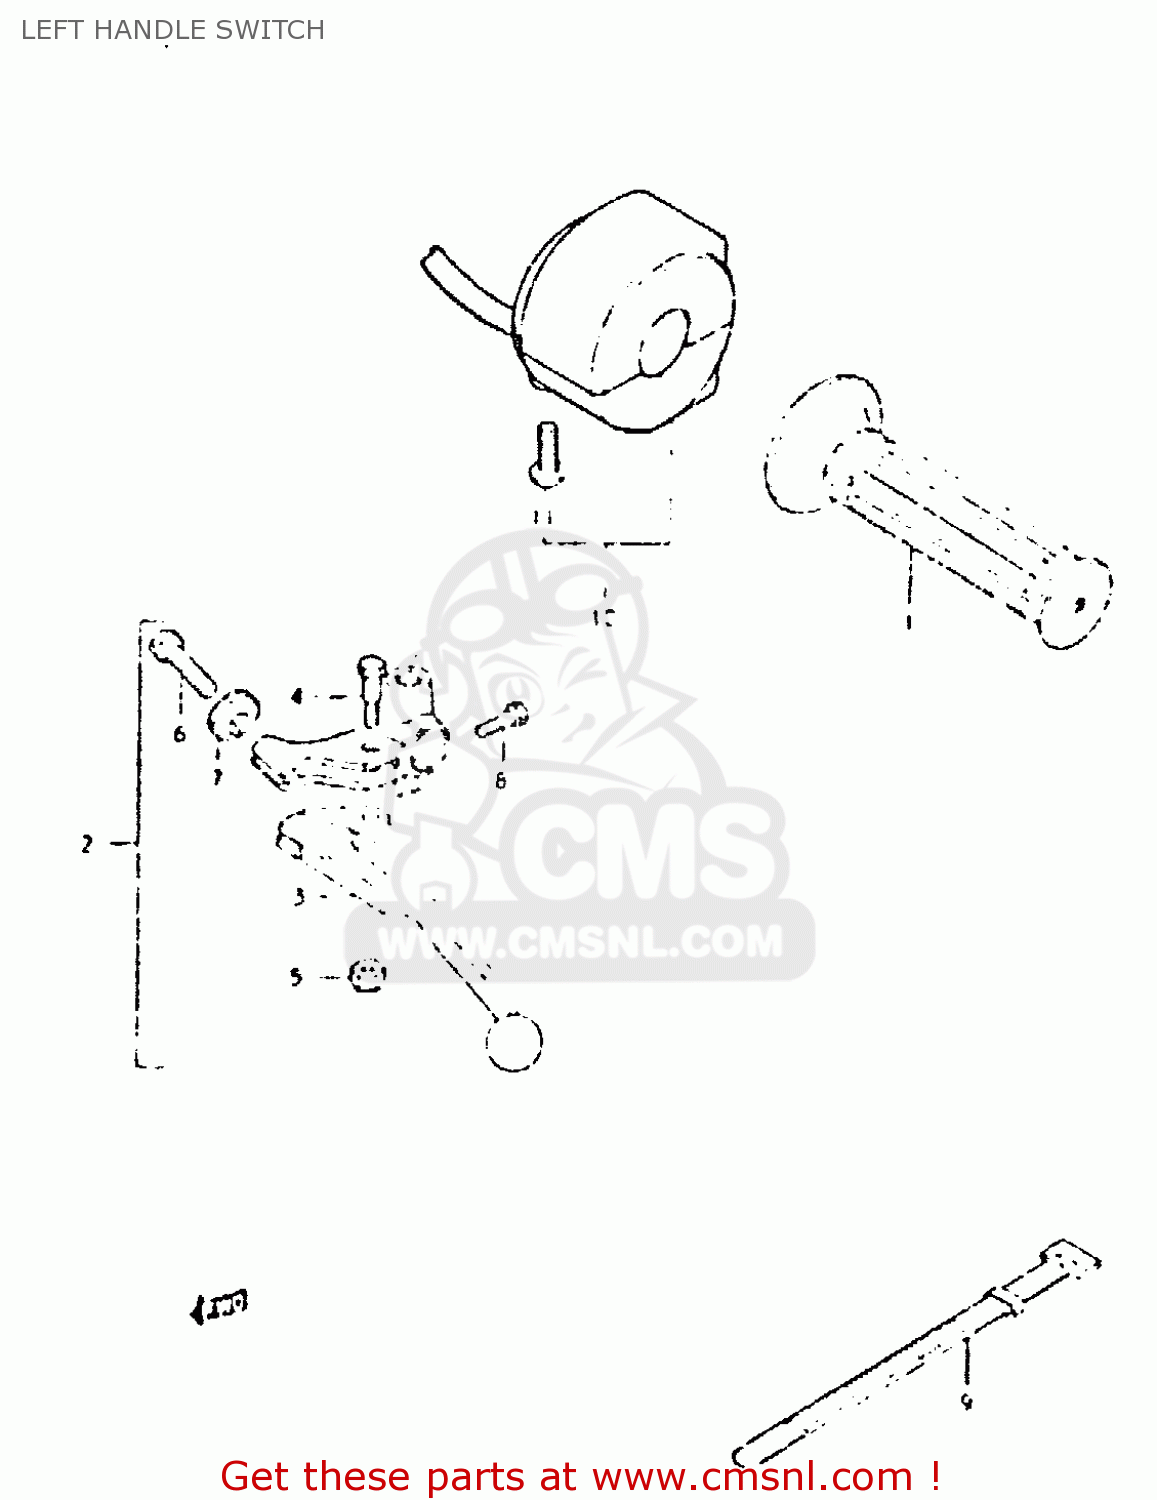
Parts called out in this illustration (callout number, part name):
1	GRIP,LEFT
2	LEVER ASSEMBLY
3	LEVER,CLUTCH
4	BOLT
5	NUT 6MM
6	ADJUSTER,CABLE
7	NUT,CABLE ADJUSTER
8	BOLT,CLUTCH LEVER HOLDER
9	CLAMP(L:120)
10	SWITCH ASSY, HANDLE LH
11	SCREW
